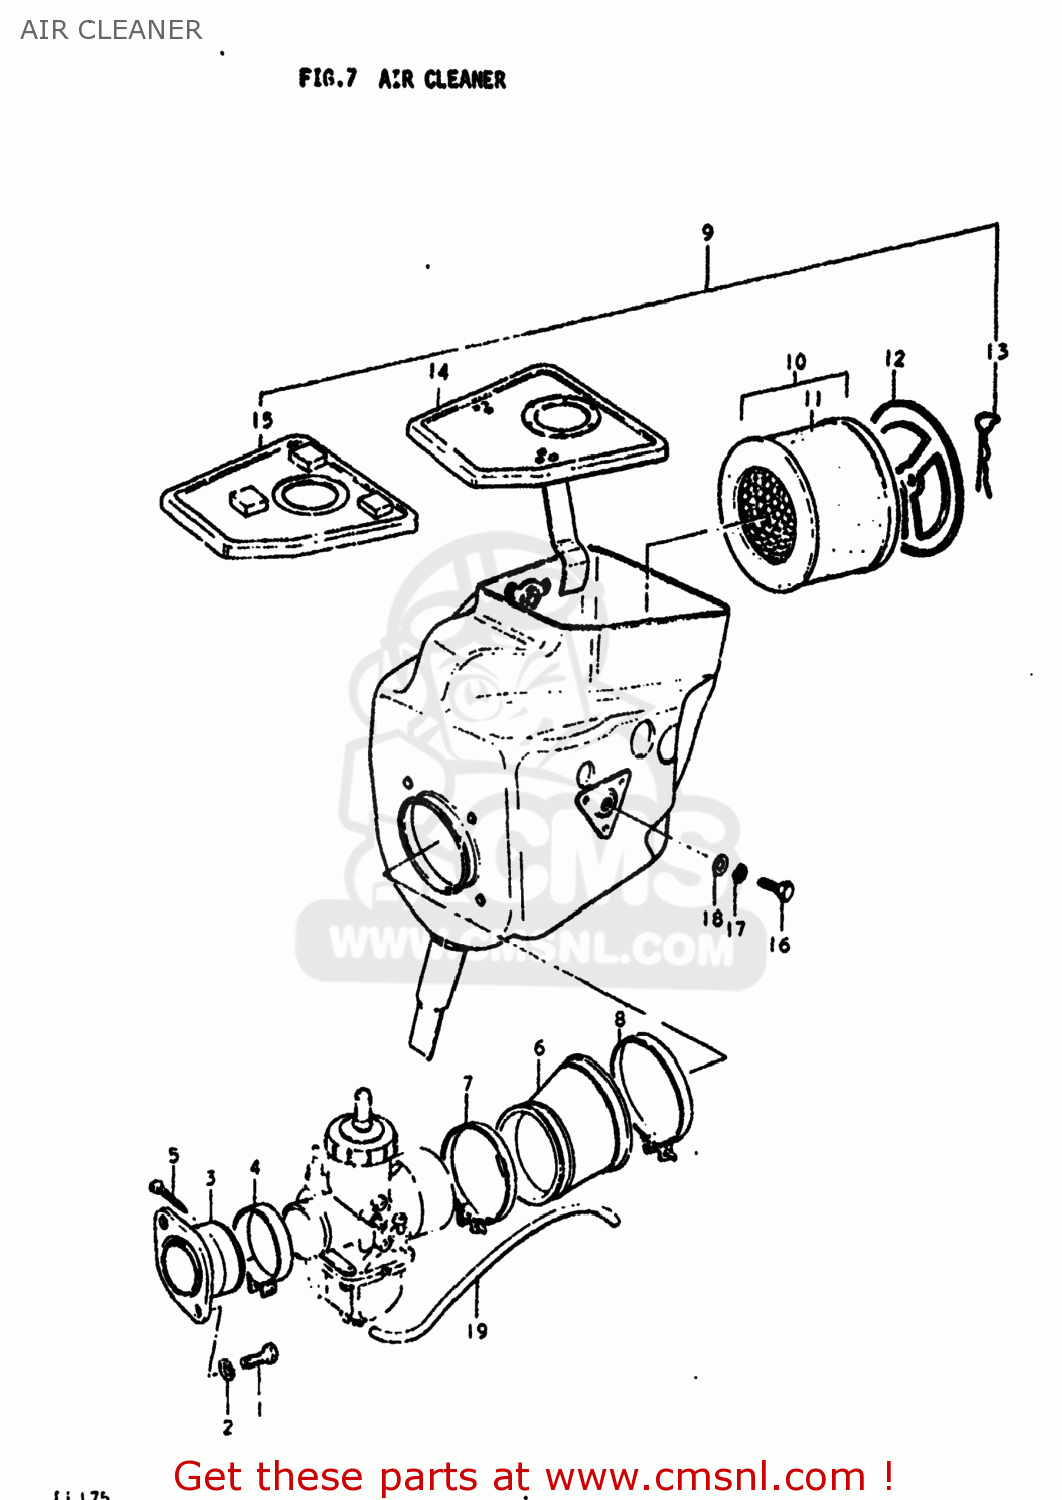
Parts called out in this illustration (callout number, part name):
1	BOLT
2	LOCK WASHER
3	PIPE,INTAKE
4	CLAMP
5	SCREW 5X20
6	HOSE,CARBURETOR AIR INLET
7	CLAMP
8	CLAMP
9	CLEANER ASSEMBLY,AIR
10	FILTER ASSY,AIR CLEANER
11	ELEMENT,AIR CLEANER
12	CAP
13	SPRING,AIR CLEANER
14	CAP,AIR CLEANER
15	CAP,AIR CLEANER
16	BOLT, UPPER
17	LOCK WASHER
18	WASHER
19	HOSE
